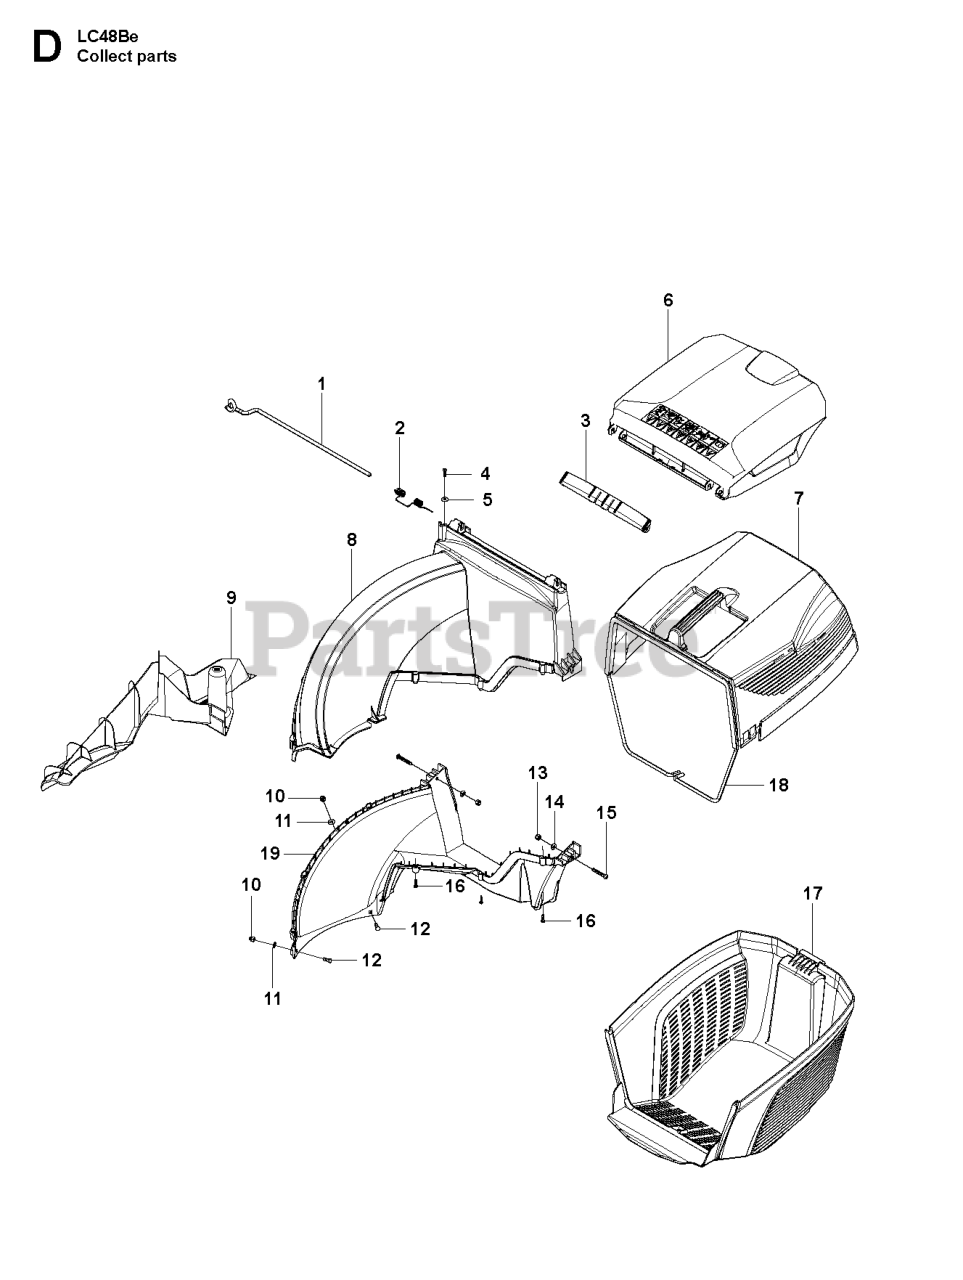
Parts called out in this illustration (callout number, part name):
1	AXLE HATCH REAR DISCHARGE
2	SPRING SAFETY FLAP A009
4	SCREW ITXPANT T50X16 ZN/FE (A
6	HATCH REAR DISCHARGE
7	GRASSBAG UPPER
8	CHUTE UPPER A009
16	SCREW ITXPANT T50X16 ZN/FE (A
17	GRASSBAG LOWER
19	CHUTE LOWER A009
